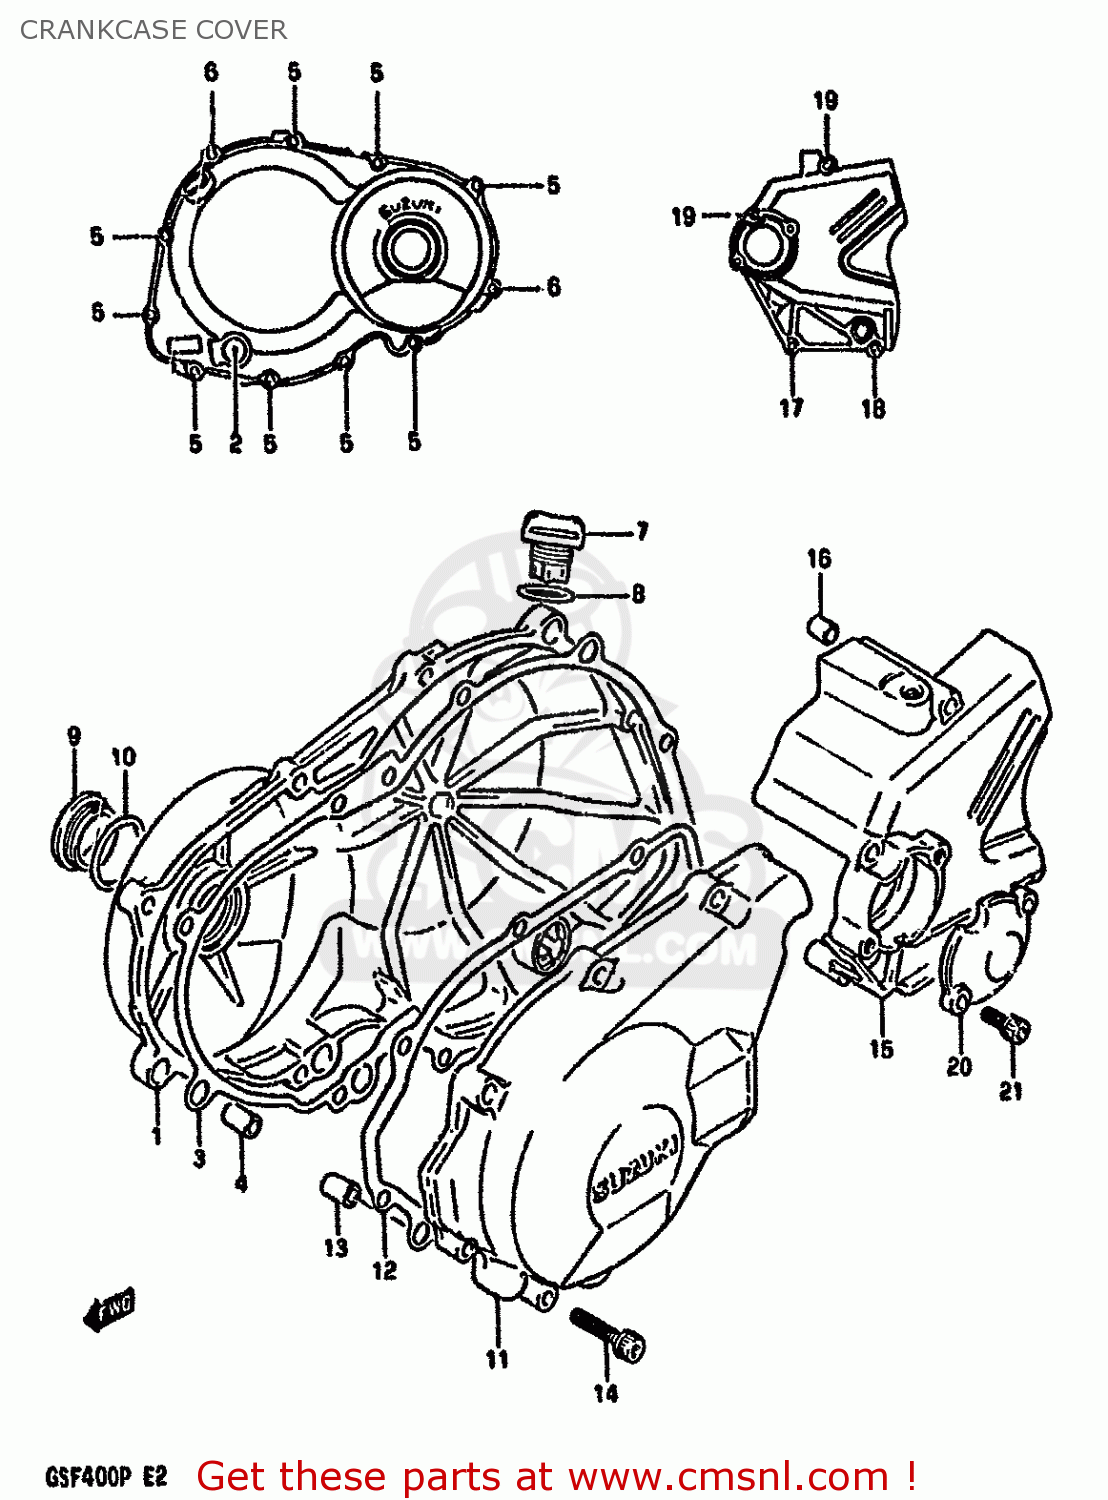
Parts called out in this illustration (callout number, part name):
1	COVER,CLUTCH
2	LENS,OIL LEVEL CHECK
3	GASKET,CLUTCH COVER (NAS)
4	PIN
5	BOLT
6	BOLT
7	PLUG,OIL FILLE
8	O RING(D:3.1,ID:16.8)
9	PLUG
10	O RING(D:3.1,ID:32.7)
11	COVER,STARTER GEAR
12	GASKET,MAGNETO COVER (NAS)
13	PIN (11X20)(SUS)
14	BOLT
15	COVER,SPROCKET
16	PIN
17	BOLT
18	BOLT
19	BOLT
20	CAP,CLUTCH RELEASE ADJUST
21	BOLT
